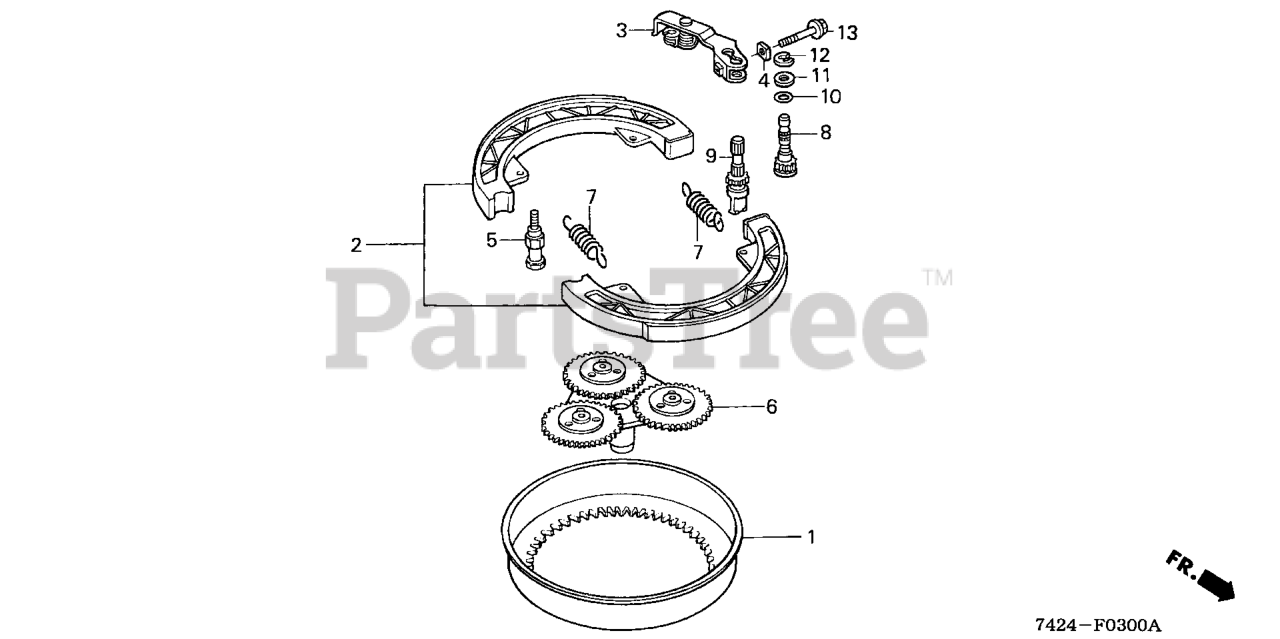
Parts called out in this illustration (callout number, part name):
1	CLUTCH (OUTER)
2	SHOE, CLUTCH
3	ARM, CLUTCH
4	PLATE, ARM LOCK
5	PIN, ANCHOR
6	PLATE, DRIVE
7	SPRING, CLUTCH SHOE
8	CAM, CLUTCH
9	CAM, SECOND CLUTCH
10	O-RING (8.8X1.9)
11	WASHER, PLAIN (12MM)
12	E-RING (10MM)
13	BOLT, FLANGE (6X32)
